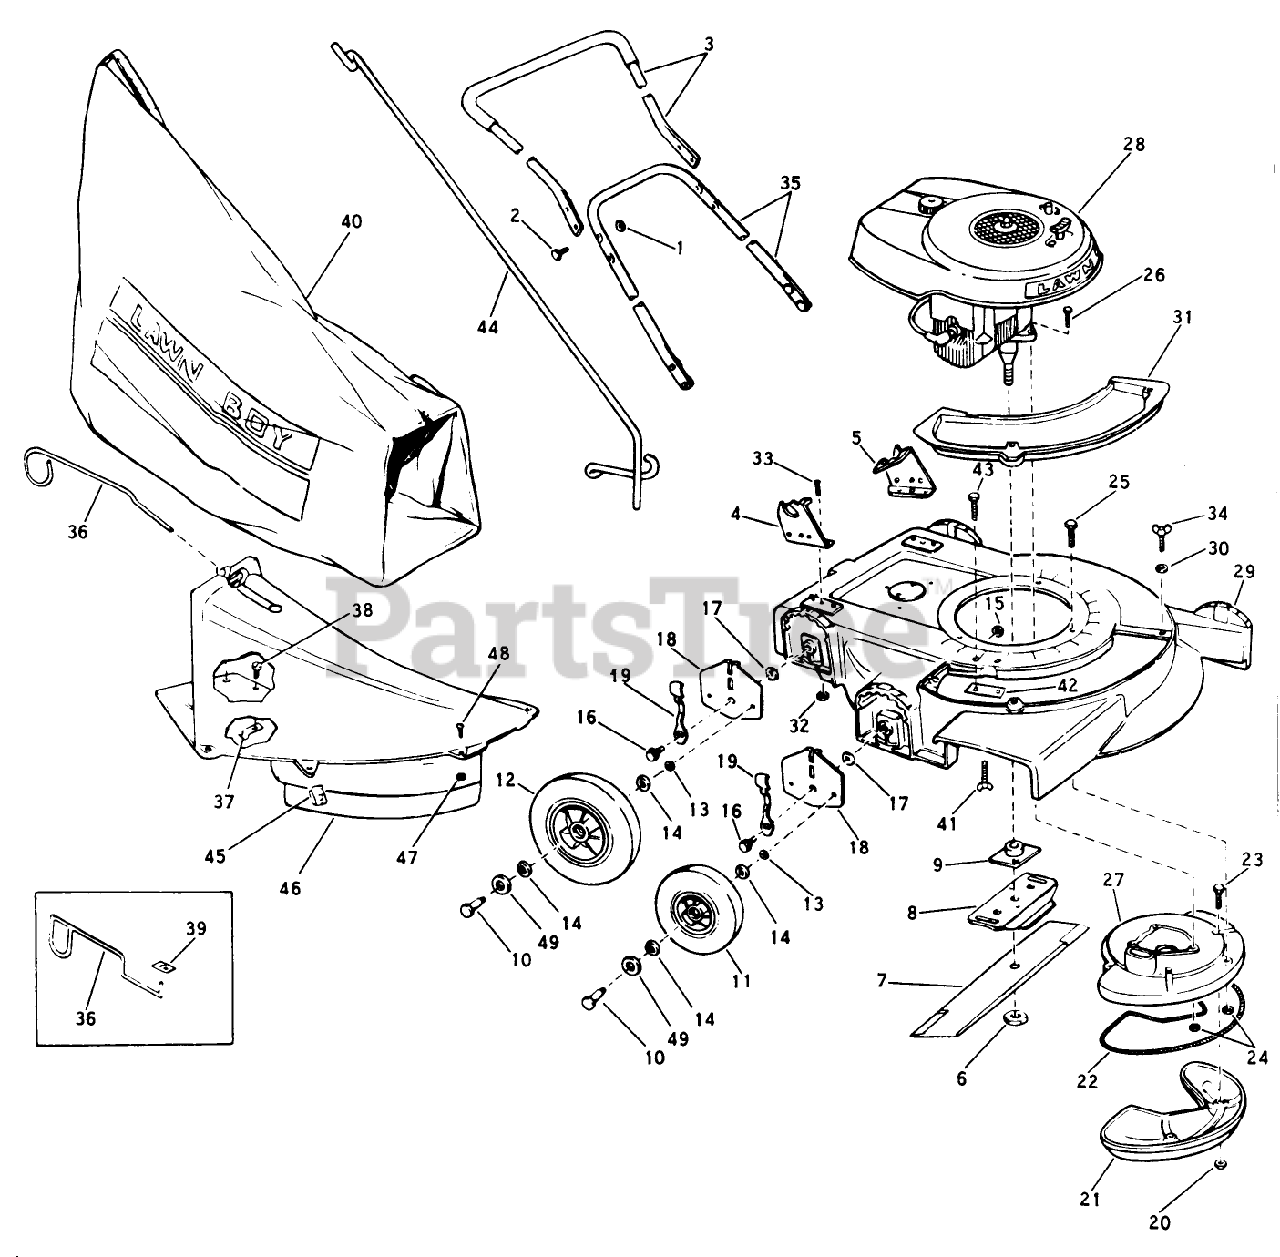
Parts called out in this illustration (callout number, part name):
3	Handle Grip Assy. Top
6	NUT-BLADE
9	PLATE AND COLLAR ASM
10	BOLT WHEEL
13	Washer-Front Wheel
14	Felt Washer
20	LOCKNUT E
29	Housing Cover Assy. 19"
33	SCREW S
40	89802 LB WHOLE GOODS
45	SPEED NUT ARDEN
46	Chute Skirt Assembly (Includes Hardware)
